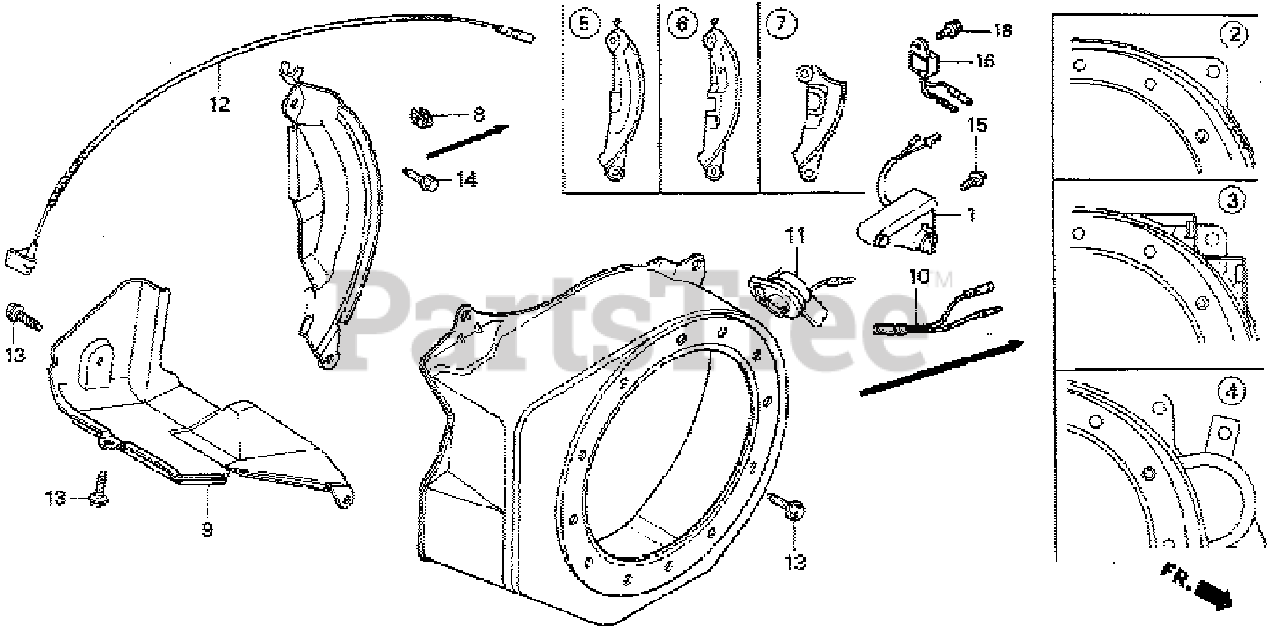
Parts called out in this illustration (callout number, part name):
1	ALERT UNIT, OIL
2	COVER, FAN *R8* (BRIGHT RED)
3	COVER, FAN *R8* (OIL ALERT) (BRIGHT RED)
5	PLATE, SIDE (STD)
5	PLATE, SIDE (OIL ALERT)
8	CLAMP, CORD
8	CLIP, HARNESS
9	SHROUD
10	SUB-HARNESS
11	SWITCH ASSY., ENGINE STOP
12	WIRE, STOP SWITCH (370MM)
13	BOLT, FLANGE (6X12) (CT200)
13	BOLT, FLANGE (6X13)
14	BOLT, FLANGE (6X20) (CT200)
15	BOLT, FLANGE (6X8)
